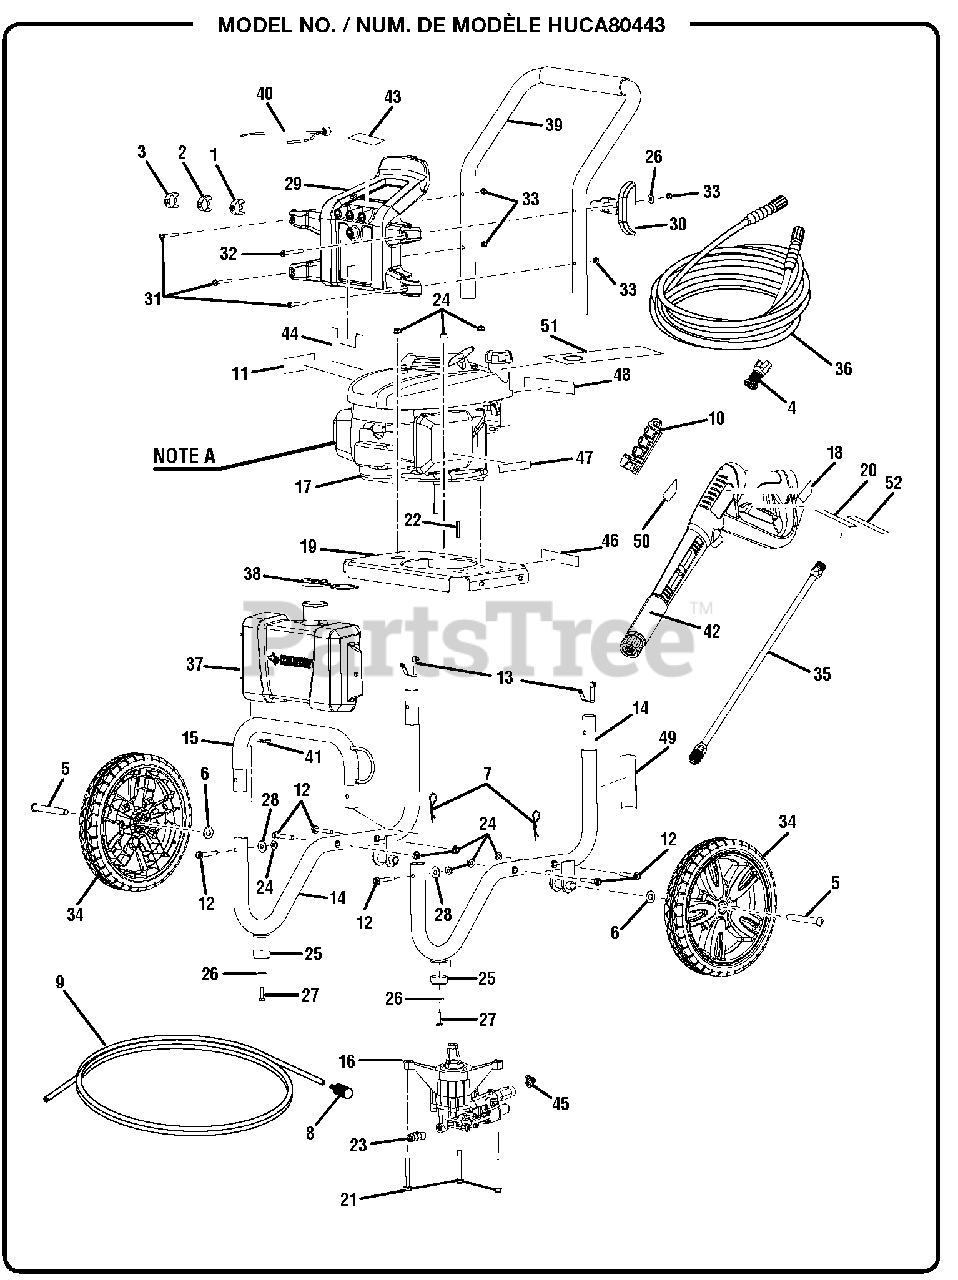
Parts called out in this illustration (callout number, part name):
1	0deg Nozzle
2	40deg Nozzle
3	25deg Nozzle
4	Soap Blaster(TM) Nozzle
5	Axle
6	Washer (1/2 in.)
7	Hitch Pin
9	Injection Hose
10	Nozzle Holder (4 Nozzle)
11	Hot Surface Label
12	Bolt w/Washer M8 x 55 mm, Hex Hd.)
13	Lock Button w/Spring Clip
14	Main Frame Assembly
15	Front Frame
16	Pump
17	Engine (Honda)
18	Trigger Handle Logo Label
19	Engine Plate
20	Spray Wand Label (Fr./Sp.)
21	Bolt (M8 x 65 mm)
22	Output Shaft Key
23	Thermal Release Valve
24	Flange Nut (M8 x 1-1/4 in.)
26	Washer (1/4 in.)
27	Bolt (1/4-20 x 1 mm, Hex Hd.)
28	Washer (5/16 in.)
29	Hose and Nozzle Holder
30	Wand Holder
31	Screw (1/4-20 x 1.85 in., Torx)
32	Screw (1/4-20 x 2.27 in., Torx)
33	Lock Nut (1/4-20)
34	Wheel (12 in. x 2 in.)
35	Spray Wand
36	High Pressure Hose
37	Soap Tank
38	Soap Tank Cap
39	Handle Assembly
40	Bungee Cord and Bead Assembly
41	Injection Hose Holder
42	Trigger Handle Assembly
43	Nozzle Label
44	Performance Label
45	Filter Screen
46	Data Label
47	Engine Quick Start Label
48	Warning Label
49	Pump Quick Start Label
50	Trigger Handle Warning Label
51	Engine Oil Fill Label
52	Wand Label (Max Rating)
53	Detergent Suction Kit
